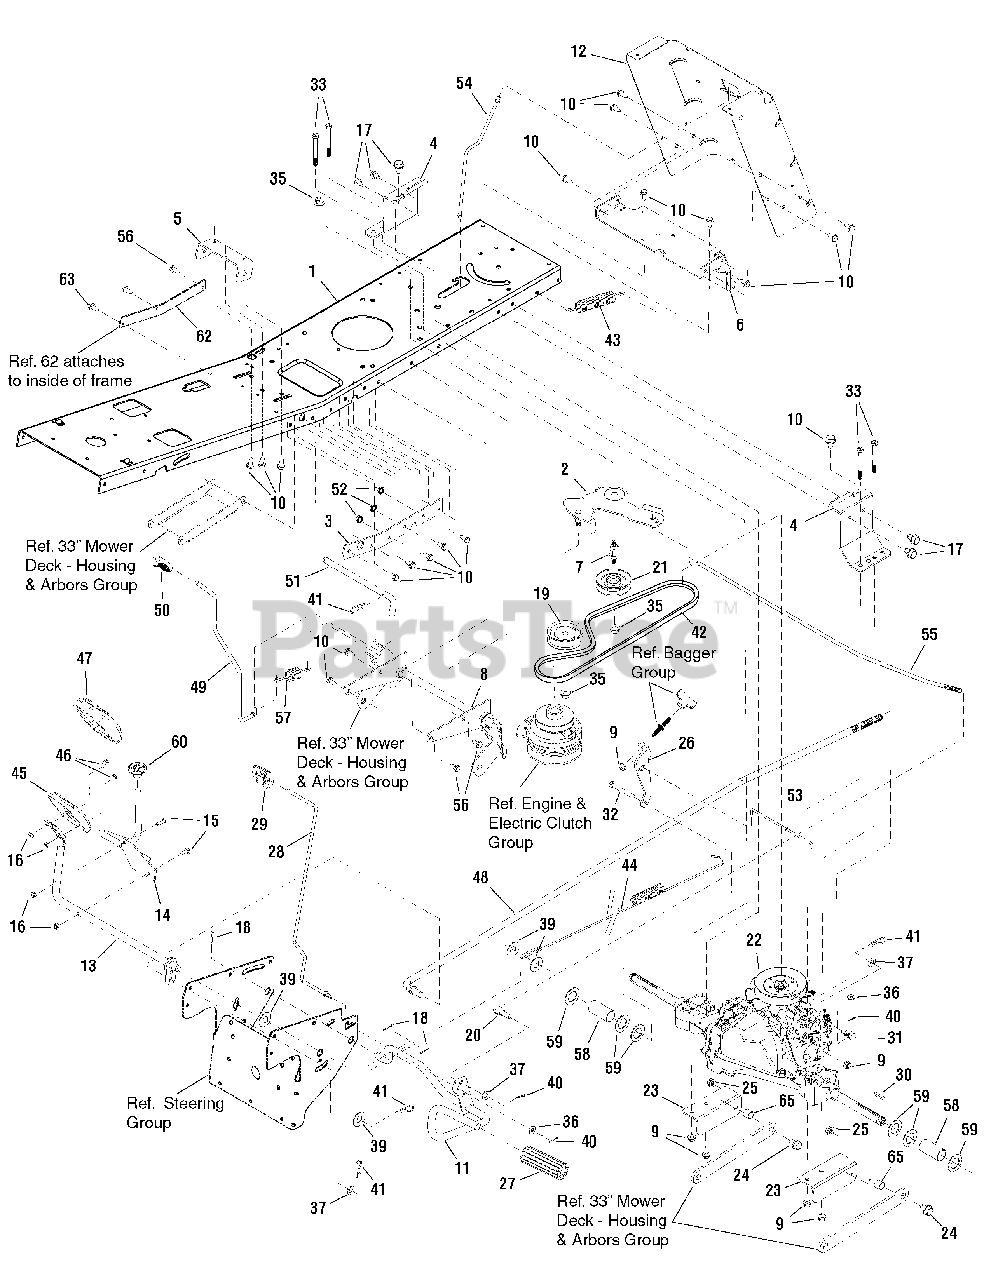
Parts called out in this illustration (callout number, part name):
1	FRAME
2	IDLER PULLEY ARM ASSY
3	REINFORCEMENT PLATE, L.H.
4	BRACKET, Transaxle
5	BRACKET, Front Hanger Pivot
6	PLATE, Hitch
7	IDLER STUD
8	LIFTER ASSEMBLY
9	NUT, Hex Flange Lock, 5/16-18
10	CAPSCREW, 5/16-18 x 3/4
11	CLUTCH & BRAKE PEDAL ASSEMBLY
12	PLATE, Rear
13	HYDRO ARM ASSY
14	REVERSE PEDAL ASSY
15	BOLT, Carriage, 1/4 - 20 x 1
16	NUT, Centerlock, 1/4-20
17	SCREW, 5/16-18 x 1/2
18	PIN, Cotter
19	IDLER PULLEY, Backside
20	NUT, Adjusting
21	IDLER PULLEY, Fixed
22	* TRANSMISSION, Hydro Gear
23	REAR HANGER BRACKET, R.H.
24	PIN, Threaded Shoulder, 3/8-16 x 1-1/2
25	NUT, Hex Flange 3/8-16
26	TORQUE STRAP BRACKET
27	PEDAL, Clutch and Brake
28	ROD, Parking Brake
29	KNOB, Parking Brake
30	KEY, Square
31	NUT, Adjusting
32	BOLT, Hex, 5/16-18 x 2-1/2
33	BOLT, Hex-Head 5/16-18 x 3
35	NUT, Flange Lock, 3/8-16
36	WASHER, Flat, 3/4
37	WASHER, Flat 3/8
39	WASHER, 0.641 x 1.38
40	PIN, Cotter, 3/4
41	HAIR PIN, .56D-.092T
42	BELT, Drive, 33"
43	SPRING, Extension
44	Spring, Brake Extension
45	PEDAL, Hydro
46	BOLT, Carriage 1/4-20 x 5/8
47	PAD, Hydro Pedal
48	ROD, Shift Link
49	LEVER, Lift Deck
50	GRIP, .50 Black
51	PIN, Front Hanger
52	NUT, Hex Flange 5/16-18
53	ROD, Roll Release
54	ROD, Battery
55	ROD, Clutch Hydro
56	SCREW, Self Tap 5/16-18 x 7/8
57	SPRING, Extension
58	SPACER
59	WASHER, Flat, 3/4 x 1-1/4 x 16GA
60	PEDAL PAD, Hydro Reverse
62	REINFORCEMENT PLATE, R.H.
63	CAPSCREW, Hex, 1/4-20 x 9/16
